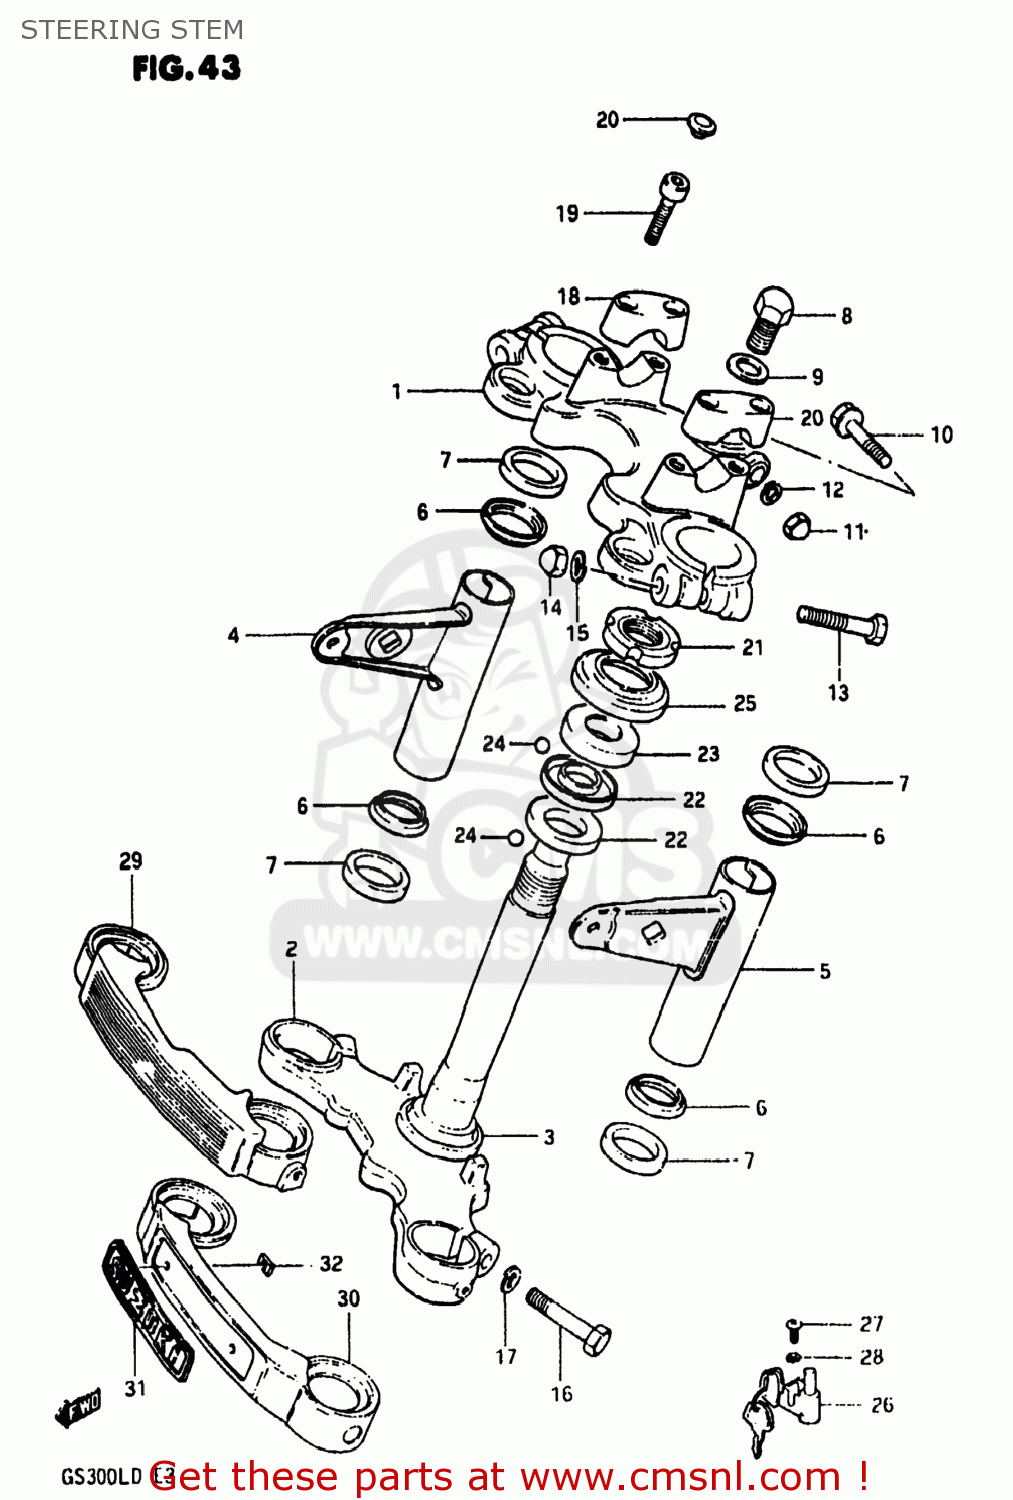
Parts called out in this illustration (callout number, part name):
1	HEAD,STEERING STEM
2	STEM,STEERING
3	RACE,STEERING OUTER LWR
4	BRACKET,HEADLAMP,RIGHT
5	BRACKET,HEADLAMP,LEFT
6	CAP,HEADLAMP BRACKET
7	CUSHION,HEADLAMP BRACKET
8	BOLT(12X20)
9	WASHER (12.5X26X1.6)
10	BOLT
11	NUT,M8X1.25X12
12	LOCK WASHER
13	BOLT 10X55
14	NUT
15	LOCK WASHER
16	BOLT 10X40
17	LOCK WASHER
18	HOLDER,HANDLEBAR(BLACK)
19	BOLT
20	CAP(OD:14.5)
21	NUT,STEERING STEM(25X44X10)
22	LACE,STEERING INNER LWR
23	LACE,STEERING OUTER UPR
24	BALL
25	DUST SEAL,STEERING UPR
26	LOCK ASSY,STEERING
27	SCREW
28	LOCK WASHER
29	COVER,FRONT FORK
30	COVER,FRONT FORK
31	EMBLEM,FR FORK COVER
32	NUT
